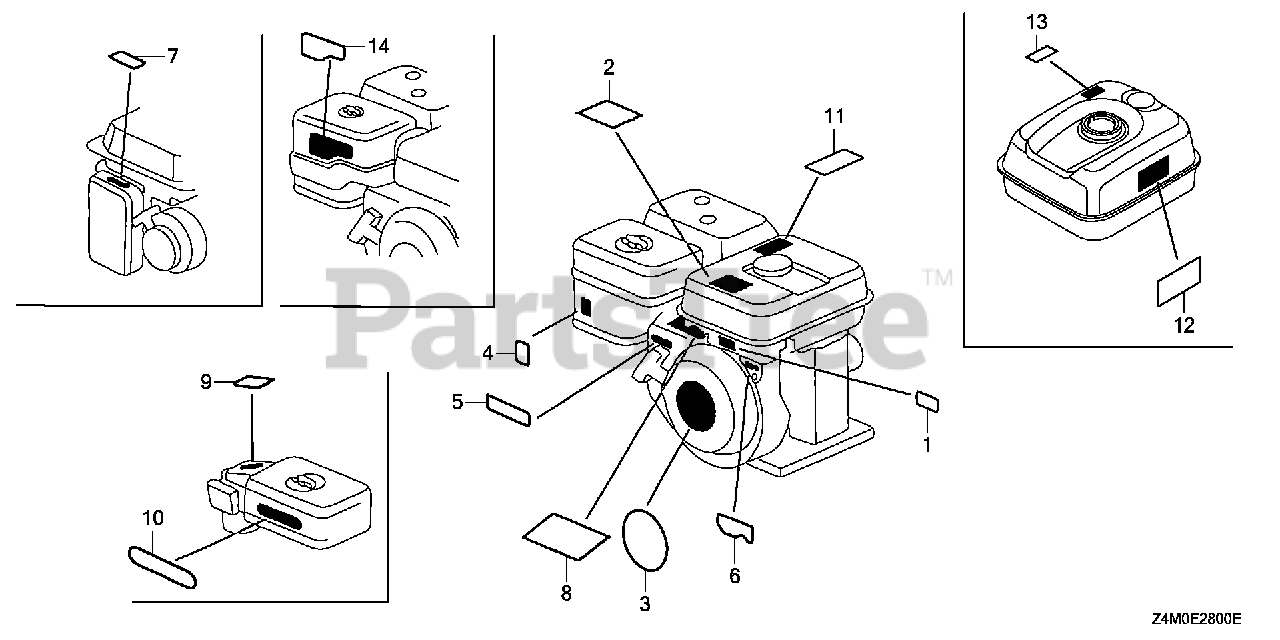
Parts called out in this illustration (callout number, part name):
3	EMBLEM (GX160)
4	MARK, CHOKE
5	MARK, THROTTLE INDICATION
12	MARK, OPERATOR CAUTION (ENGLISH)(MADE IN THAI)
13	MARK, EX. CAUTION (ENGLISH)
